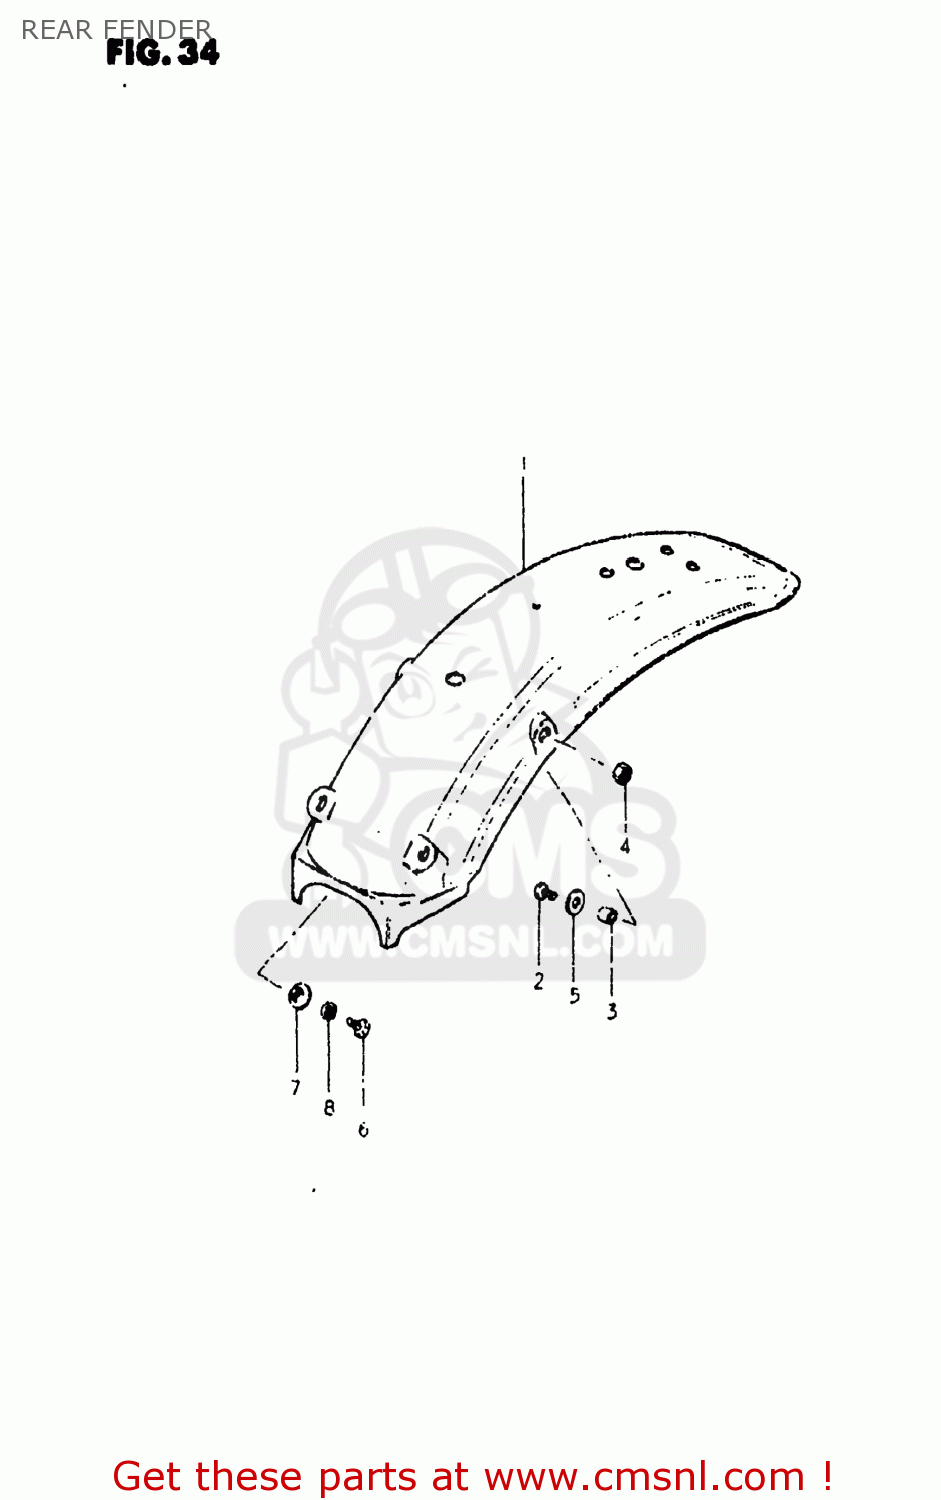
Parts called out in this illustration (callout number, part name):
1	FENDER,REAR
2	SCREW
3	SPACER
4	NUT
5	WASHER (6.5X20X1.2)
6	BOLT
7	WASHER
8	LOCK WASHER
